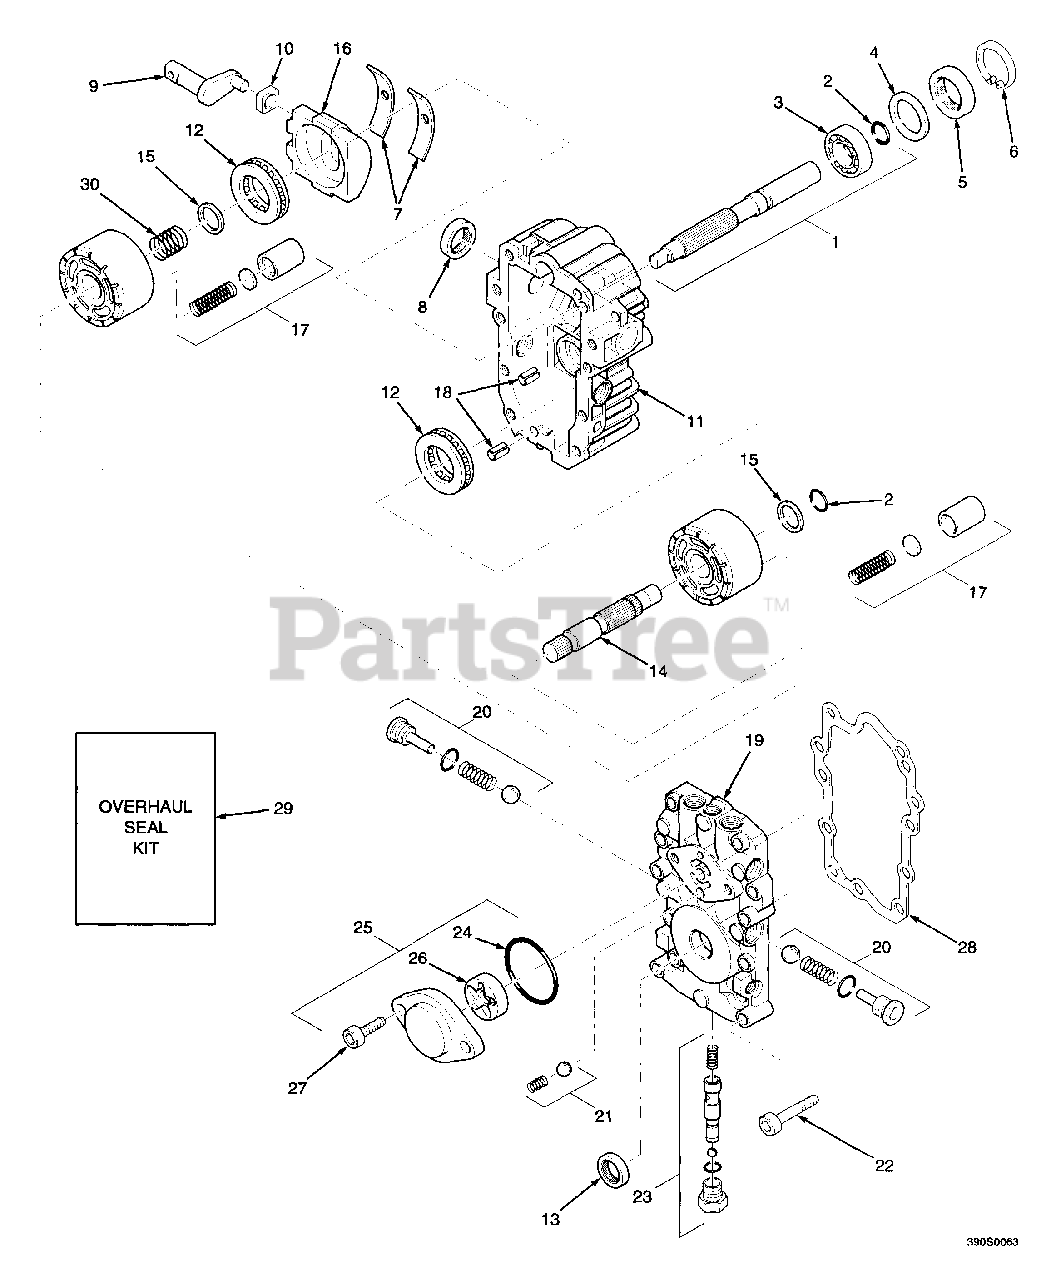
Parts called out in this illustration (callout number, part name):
1	Pump Shaft Kit
2	Wire Retaining Ring
3	Ball Bearing
5	Lip Seal (16 x 35 x 7)
6	Retaining Ring
7	Cradle Bearing
8	Lip Seal (12 x 35 x 7)
9	Trunnion Arm
10	Slot Guide
11	Transmission Housing Kit (L.H.)
11	Transmission Housing Kit (R.H.)
12	Thrust Ball Bearing Assembly
13	Lip Seal (15 x 24 x 7)
14	Motor Shaft
15	Block Thrust Washer
16	Variable Swash Plate
17	BDT-10L Block Assembly
18	Pin ST Holder
19	Center Section Kit
20	Check Valve Kit
21	Charge Relief Kit
22	Socket Head Capscrew
23	Bypass Valve Kit
25	Charge Pump Cover
26	Gerotor Assembly
27	Capscrew (6mm x 20)
28	Center Section Gasket
29	Overhaul Seal Kit
30	Spring Block
